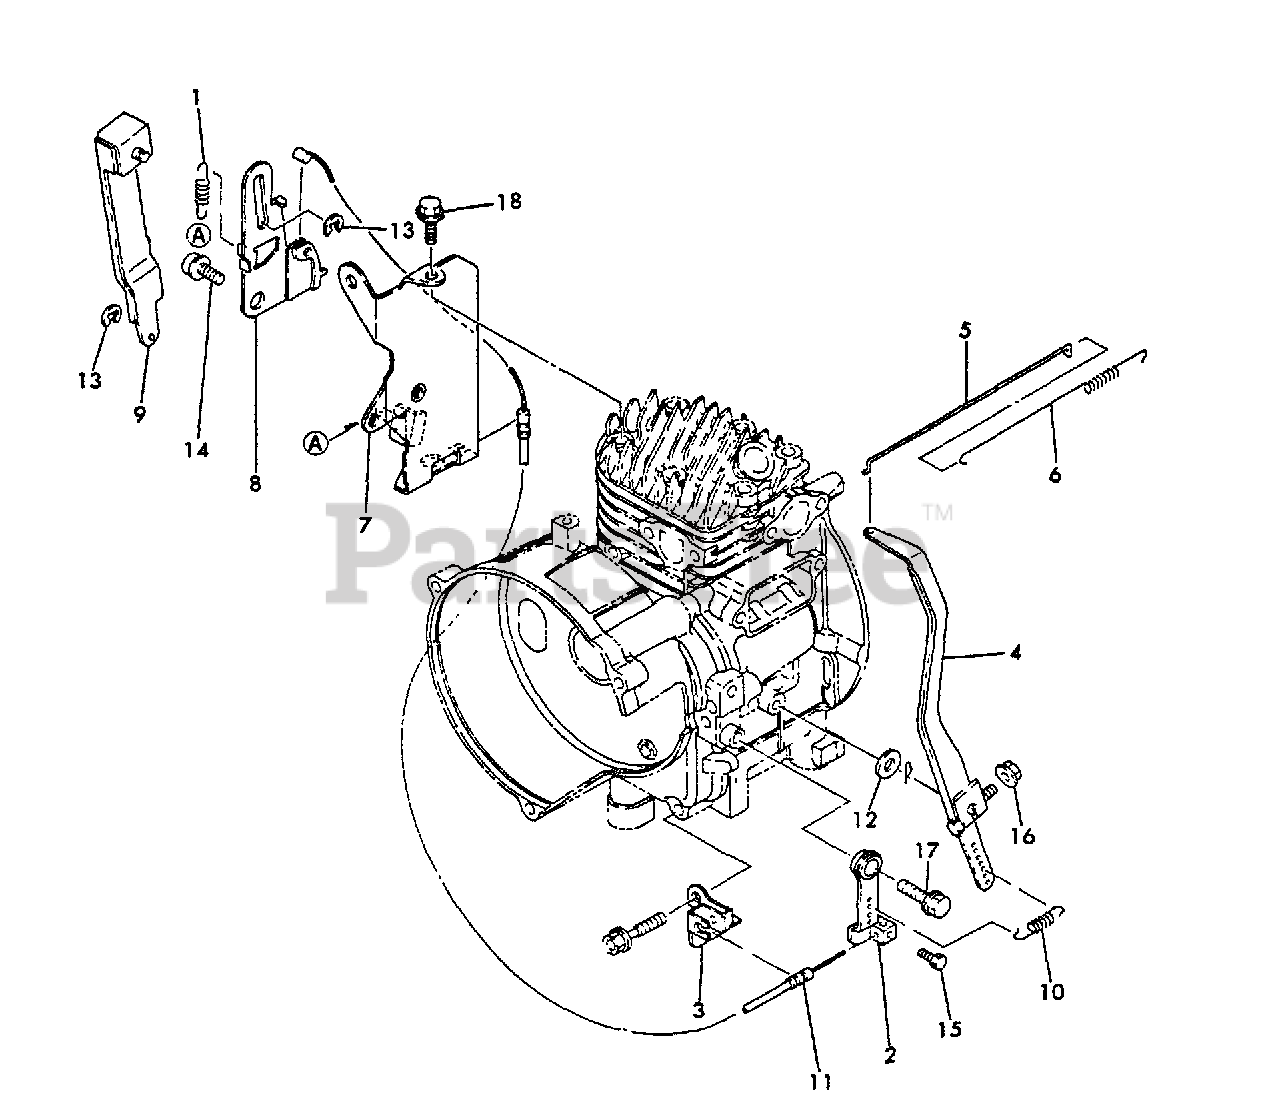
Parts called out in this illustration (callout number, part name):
1	SPRING, REGULATOR
2	HANDLE ASSY
3	WIRE HOLDER
4	LEVER, GOVERNOR
5	LINK, THROTTLE
6	SPRING, TENSION
7	BRACKET, CONT. LEVER
8	LEVER, CONTROL
9	LEVER, CONT. SHIFT
10	SPRING, CONT. LEVER
11	THROTTLE CABLE ASSY
12	WASHER
13	RING, RETAINING - 5
14	SCREW M6×10
15	BOLT - 4×8 -- PLATED
16	U-NUT M6
17	BOLT - 6×8 -- PLATED
18	BOLT - 6×8 -- PLATED
